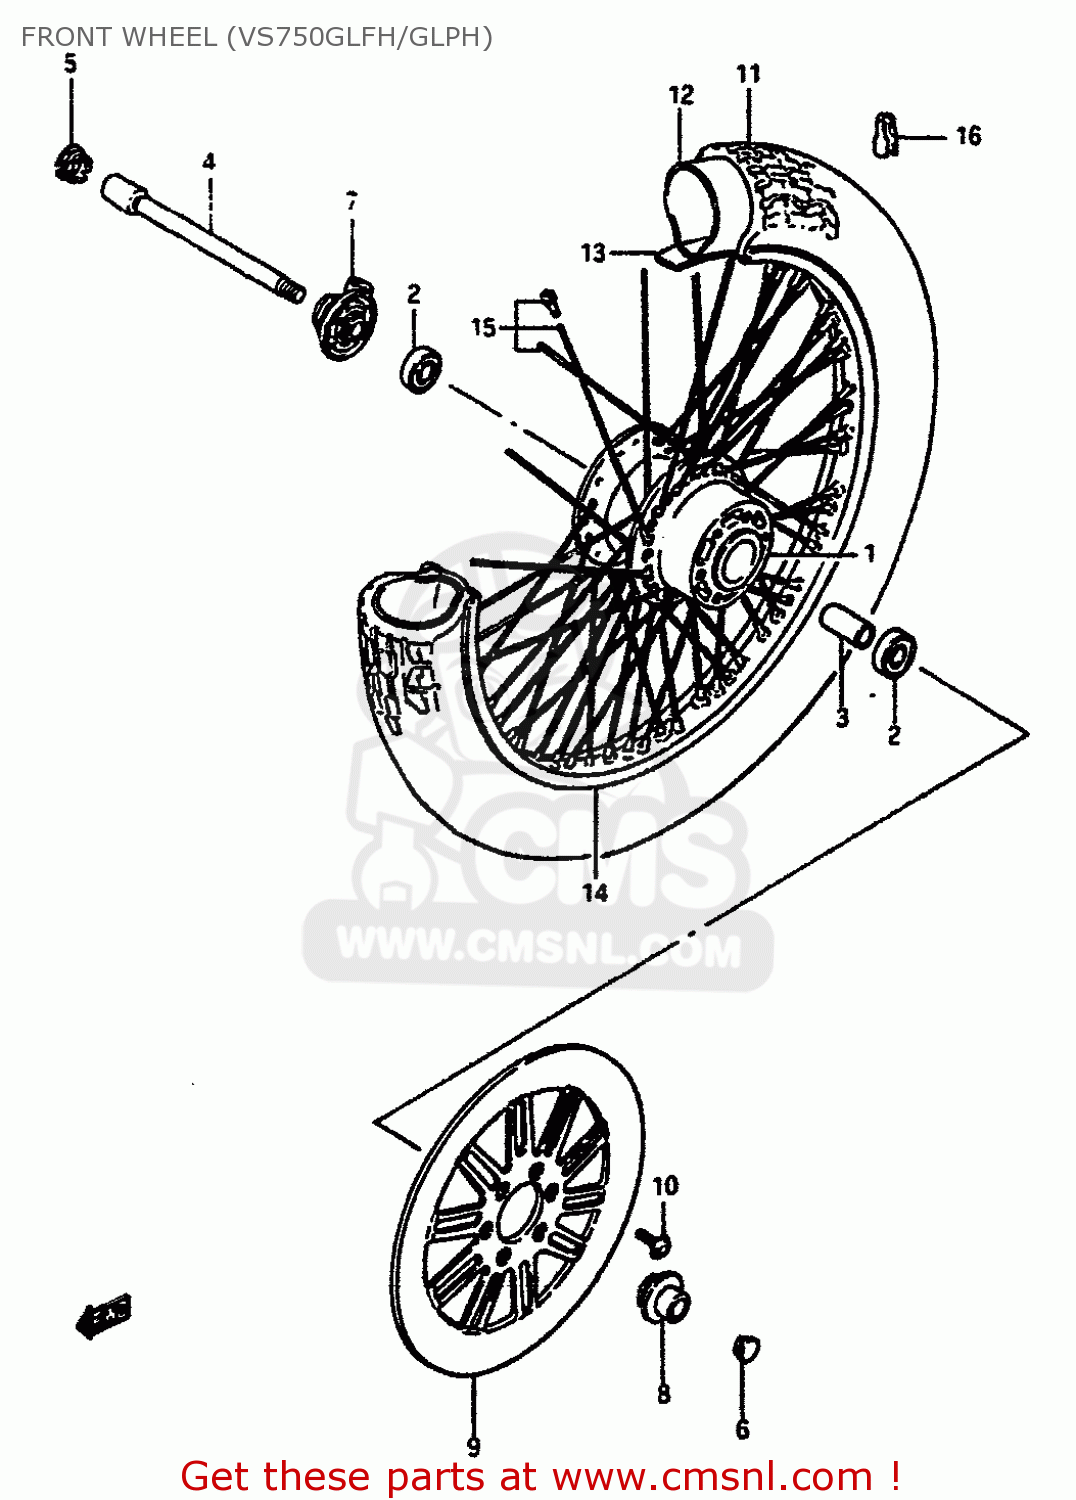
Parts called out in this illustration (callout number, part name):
1	HUB ASSY,FR
2	BEARING
3	SPACER(15.3X21.7X65)
4	AXLE,FRONT
5	CAP,FR AXLE
6	CAP,FR AXLE
7	BOX ASSY,SPEEDOMETER GEAR
8	SPACER COMP,FRONT AXLE
9	DISC,FR BRAKE
10	BOLT(8X25.5)
11	TIRE,FRONT
12	TUBE,INNER
13	PROTECTOR,WHL INR TUBE
14	RIM,FRONT WHEEL (MT2.15)
15	SPOKE SET,FR WHEEL
16	BALANCER,WHEEL
